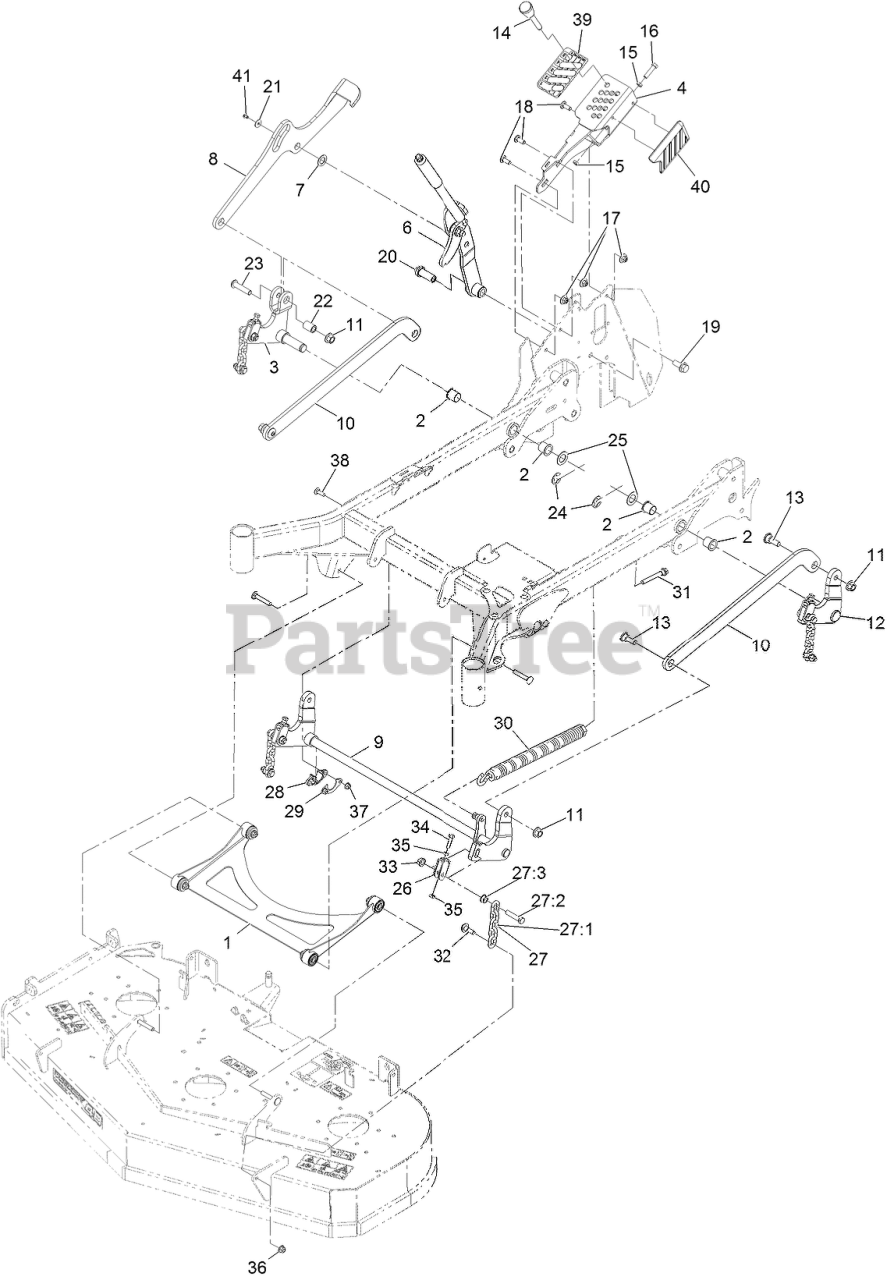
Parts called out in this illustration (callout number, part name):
1	ASM, Deck Strut
2	BUSHING, IGUS
3	Weld, Bellcrank, Rt
4	Weld, HOC Index
6	ASM, HOC Lever
7	WASHER-THRUST
8	Strap, HOC Index
9	Weld, HOC Cross Shaft
10	Strap, HOC Lift
11	Nut-Lock 1/2-13
12	Weld, Bellcrank
13	Bolt, Shoulder
14	PIN-HOC
15	NUT-JAM
16	BOLT-HH
17	Nut-Nyloc 3/8-16 Flg
18	SCREW-CARR
19	SCREW-HHF
20	Pivot, HOC Lever
22	Spacer, HOC
23	Screw-HSBH
24	RING-RETAINING, EXT
25	Washer-Flat
26	YOKE-ADJUST, DECK
27	DECK LIFT CHAIN ASM
27:1	CHAIN-LIFT, DECK
27:2	SCREW-HH
28	BUSHING-FLANGE
29	GUSSET-LIFT, DECK
30	SPRING-EXTENSION
31	BOLT-SHOULDER
32	SCREW-SHOULDER, HHF
34	SCREW-HH
35	NUT-JAM
36	NUT-HF, NI
37	NUT-HF, NI
38	BOLT-CARR
39	Decal-Height Of Cut
40	Pad, Knee
41	Screw, 1/4-20 X 3/8 PH Torx
